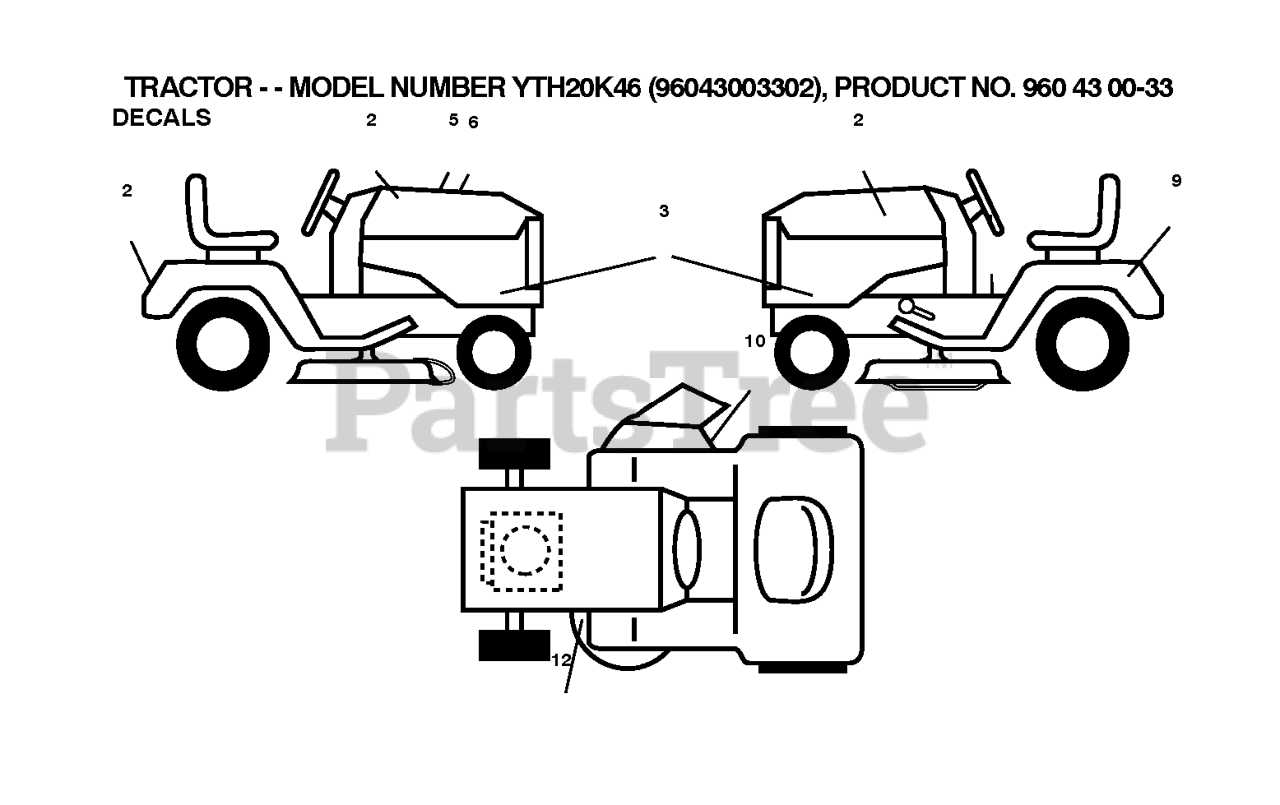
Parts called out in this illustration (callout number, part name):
2	VALVE STEM LT
3	RIM ASM 6" FRONT SILVER
4	TUBE.5.3/4.5/6
5	TIRE HEAVY DUTY
6	FITTING LT
7	BEARING T
8	CAP, AXLE BLK
9	TIRE.18X9.5-8 TURF SAVER
10	TUBE
11	RIM ASM 8" REAR SILVER
